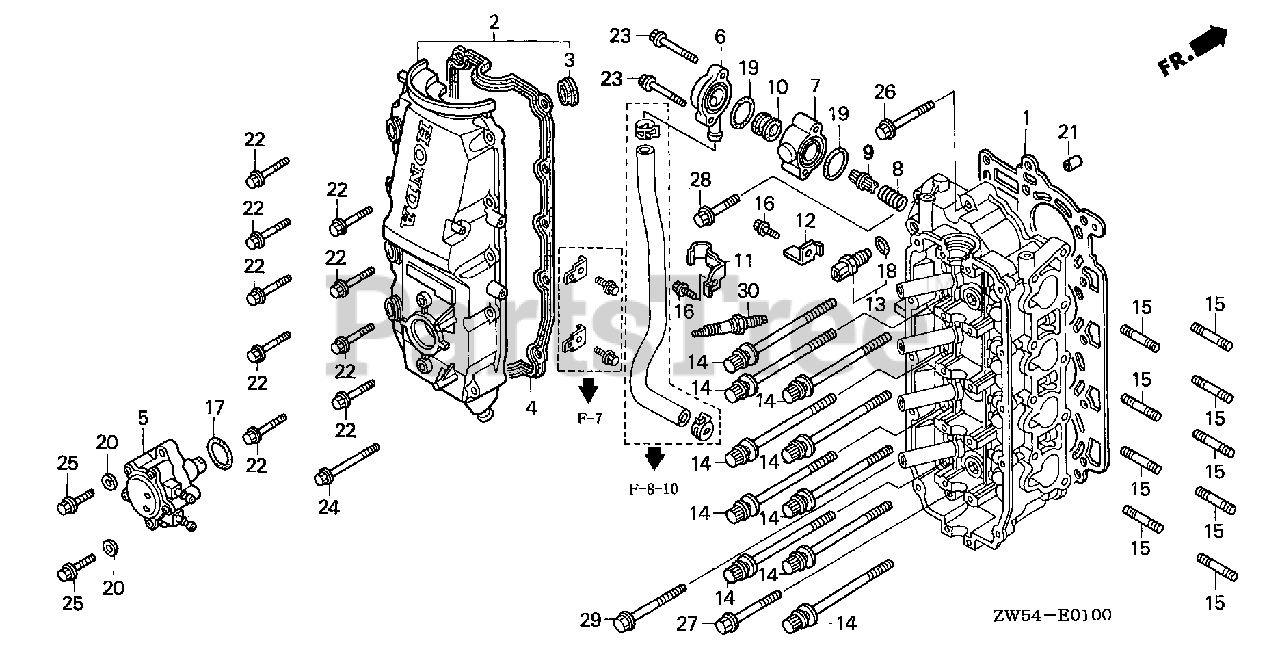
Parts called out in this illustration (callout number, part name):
1	GASKET, CYLINDER HEAD
2	COVER, HEAD *NH8* (DARK GRAY)
3	SEAL, SPARK PLUG TUBE (NOK)
4	GASKET, HEAD COVER
5	PUMP ASSY., FUEL
6	COVER, FLUSH VALVE
7	SPACER, FLUSH VALVE *NH8* (DARK GRAY)
8	SPRING, FLUSH VALVE
9	VALVE, RELIEF
10	GASKET, RELIEF VALVE
11	CLAMP, HOSE
12	STAY A, IGNITION WIRE CLAMP
13	SENSOR ASSY., WATER TEMPERATURE
14	BOLT-WASHER (12X163)
15	BOLT, STUD (10X32)
16	BOLT, FLANGE (6X12)
17	O-RING (37X2.4) (ARAI)
18	O-RING (9.5X1.5) (HONDA KIKAKI)
19	O-RING (31.5X2.4) (ARAI)
20	WASHER, PLAIN (8MM)
21	PIN, DOWEL (14X20)
22	BOLT, FLANGE (6X35)
23	BOLT, FLANGE (6X55)
24	BOLT, FLANGE (6X65)
25	BOLT, FLANGE (8X32)
26	BOLT, FLANGE (8X50)
27	BOLT, FLANGE (8X80)
28	BOLT, FLANGE (10X70)
29	BOLT, FLANGE (10X90)
30	SPARK PLUG (KJ22CR-L8)
30	SPARK PLUG (ZFR7F)
